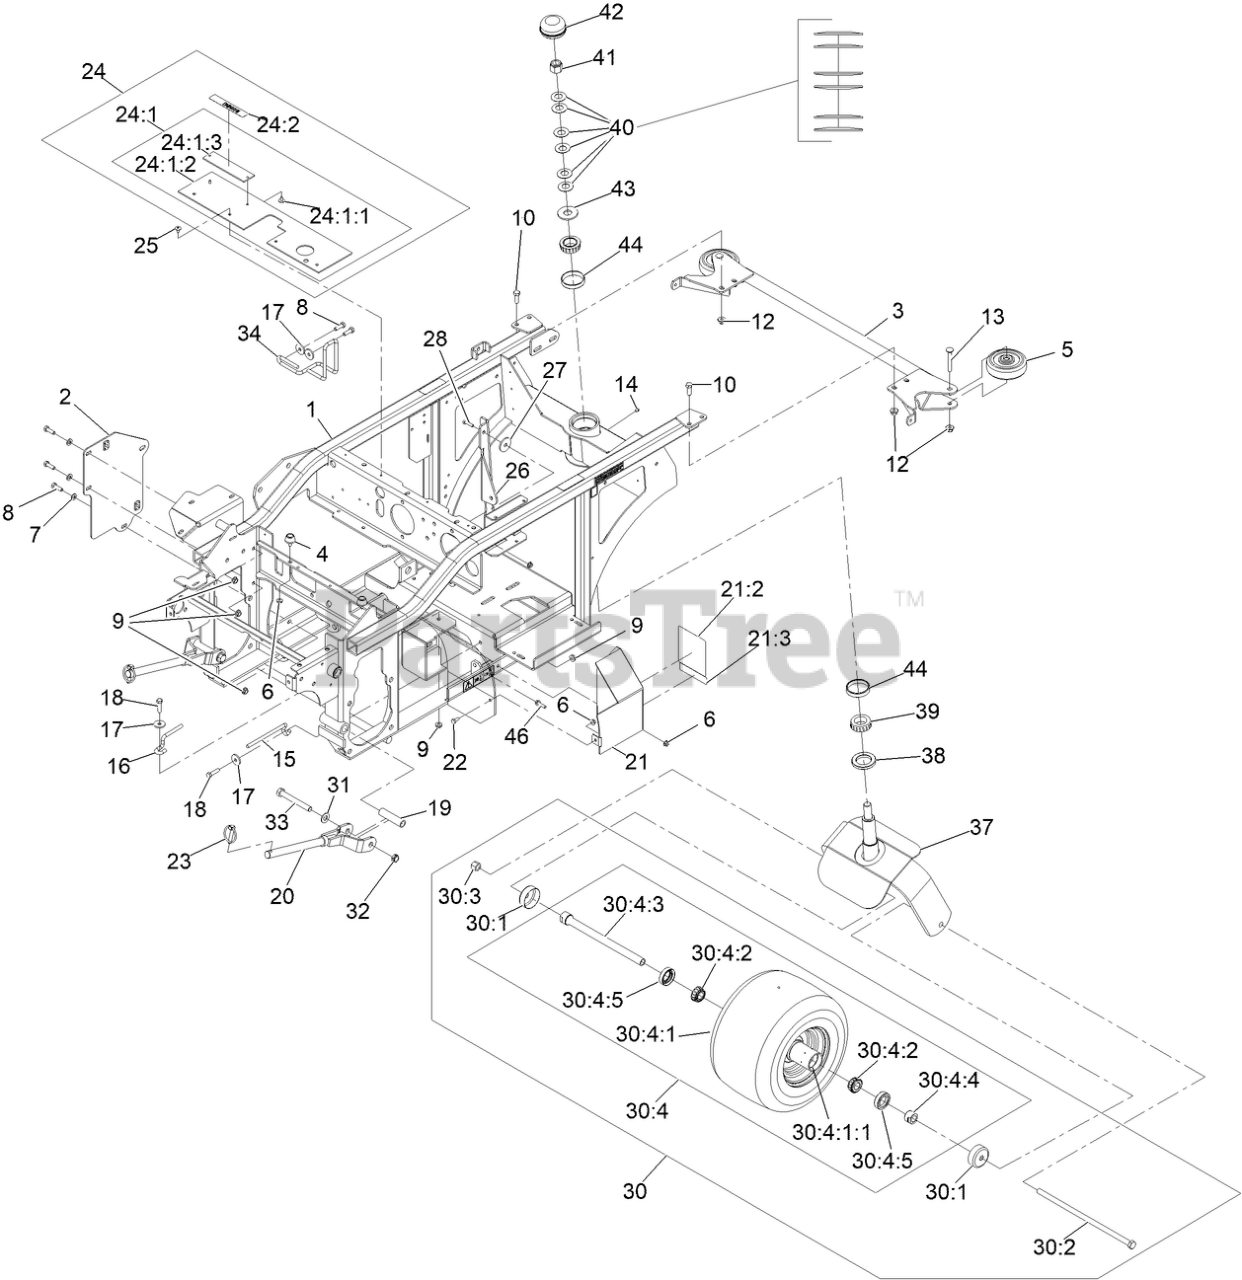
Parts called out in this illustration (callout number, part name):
1	FRAME ASM
2	PLATE-SUPPORT
3	BUMPER-REAR
4	BUMPER-RUBBER
5	ROLLER-BUMPER
6	NUT-HF
7	WASHER-PLAIN
8	SCREW-HH
9	NUT-HF
10	SCREW-HH
12	NUT-HF, NI
13	SCREW-CARR
15	GUIDE-BELT
16	GUIDE-BELT
17	WASHER
18	SCREW-HH
19	SPACER-WHEEL, SHORT
20	ROD-PUSH
21	DRIVE SHIELD ASM
21:2	DECAL-BELT ROUTING
21:3	DECAL-WARNING
22	SCREW-HH
23	PIN-LYNCH
24	LIFT SHIELD ASM
24:1	SHIELD-LIFT
24:1:1	RIVET-POP
24:1:3	PLATE-DECAL
24:2	DECAL-WARNING
25	RIVET-POP
26	BRACE-PTO
27	WASHER
28	SCREW-HH
30	WHEEL AND AXLE ASM
30:1	GUARD-SEAL
30:2	SCREW-HH
30:3	NUT-LOCK, NI
30:4	WHEEL AND BEARING ASM
30:4:1	WHEEL AND TIRE ASM
30:4:1:1	BEARING-CUP
30:4:2	BEARING-CONE, TAPER
30:4:3	AXLE CASTER ASM
30:4:4	SPACER-NUT
30:4:5	SEAL-CASTER
31	WASHER-FLAT
32	NUT-HEX
33	SCREW-HH
34	WLD-BELT GUIDE
37	FORK-REAR CASTER
38	SEAL-GREASE
39	BEARING-ROLLER, CONE TAPER
40	WASHER-BELLVILLE
41	NUT-LOCK, NI
42	CAP-GREASE
43	WASHER-FLAT
44	CUP-TAPERED, ROLLER BEARING
46	SCREW-HHF
